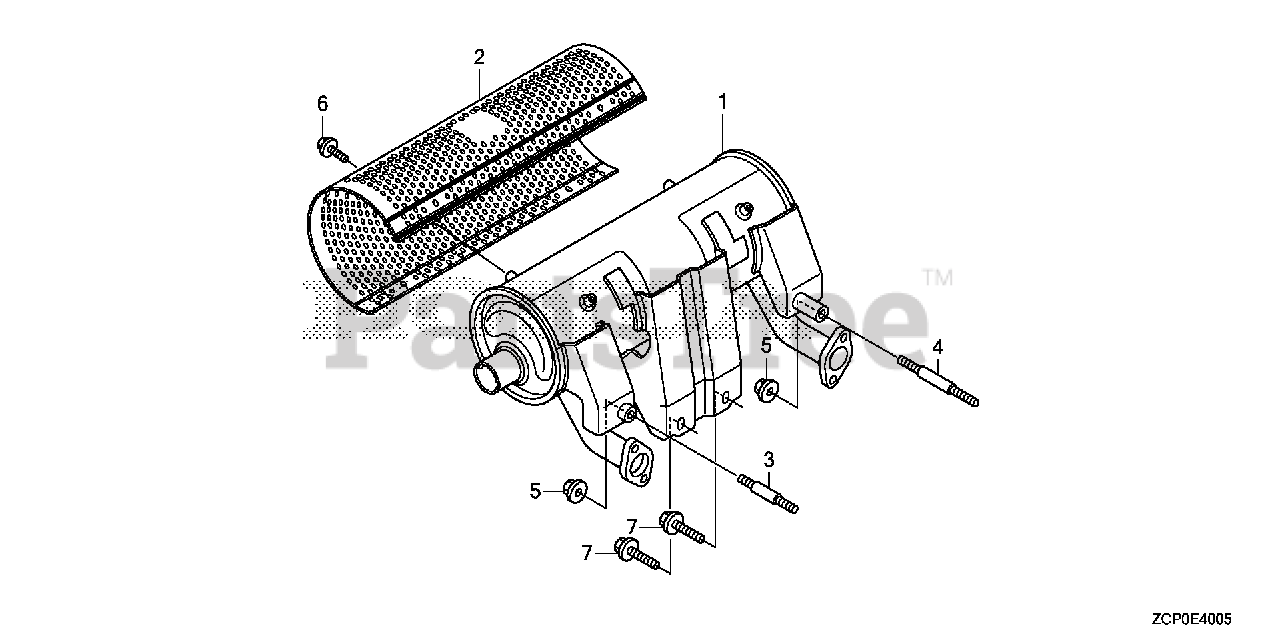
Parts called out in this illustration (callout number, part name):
1	MUFFLER (HIGH-R)
2	PROTECTOR, MUFFLER (HIGH) (FUTABA)
3	BOLT, STUD (8X45)
4	BOLT, STUD (8X60)
5	NUT, FLANGE (8MM)
6	BOLT, FLANGE (6X8)
7	BOLT, FLANGE (8X20) Use up to Engine SN 1609606.
